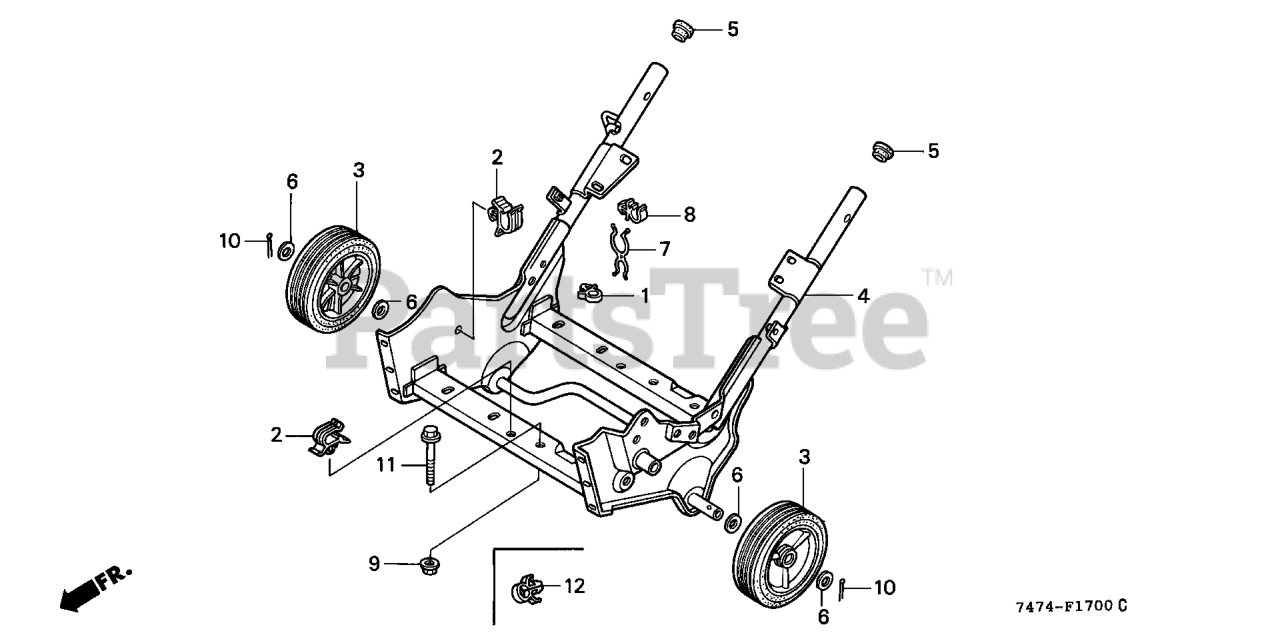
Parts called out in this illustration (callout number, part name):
1	CLIP, TUBE
2	CLIP, WIRE HARNESS
3	WHEEL (7")
4	BED, ENGINE
5	CAP, HANDLE (LOWER)
6	WASHER (13MM)
7	CLIP, WIRE HARNESS
8	CLAMP, WIRE (8MM)
9	NUT, FLANGE (8MM)
10	PIN, SPLIT (3.0X25)
10	PIN, COTTER (3.0X45)
11	BOLT, FLANGE (8X35)
12	CLIP B, CABLE
